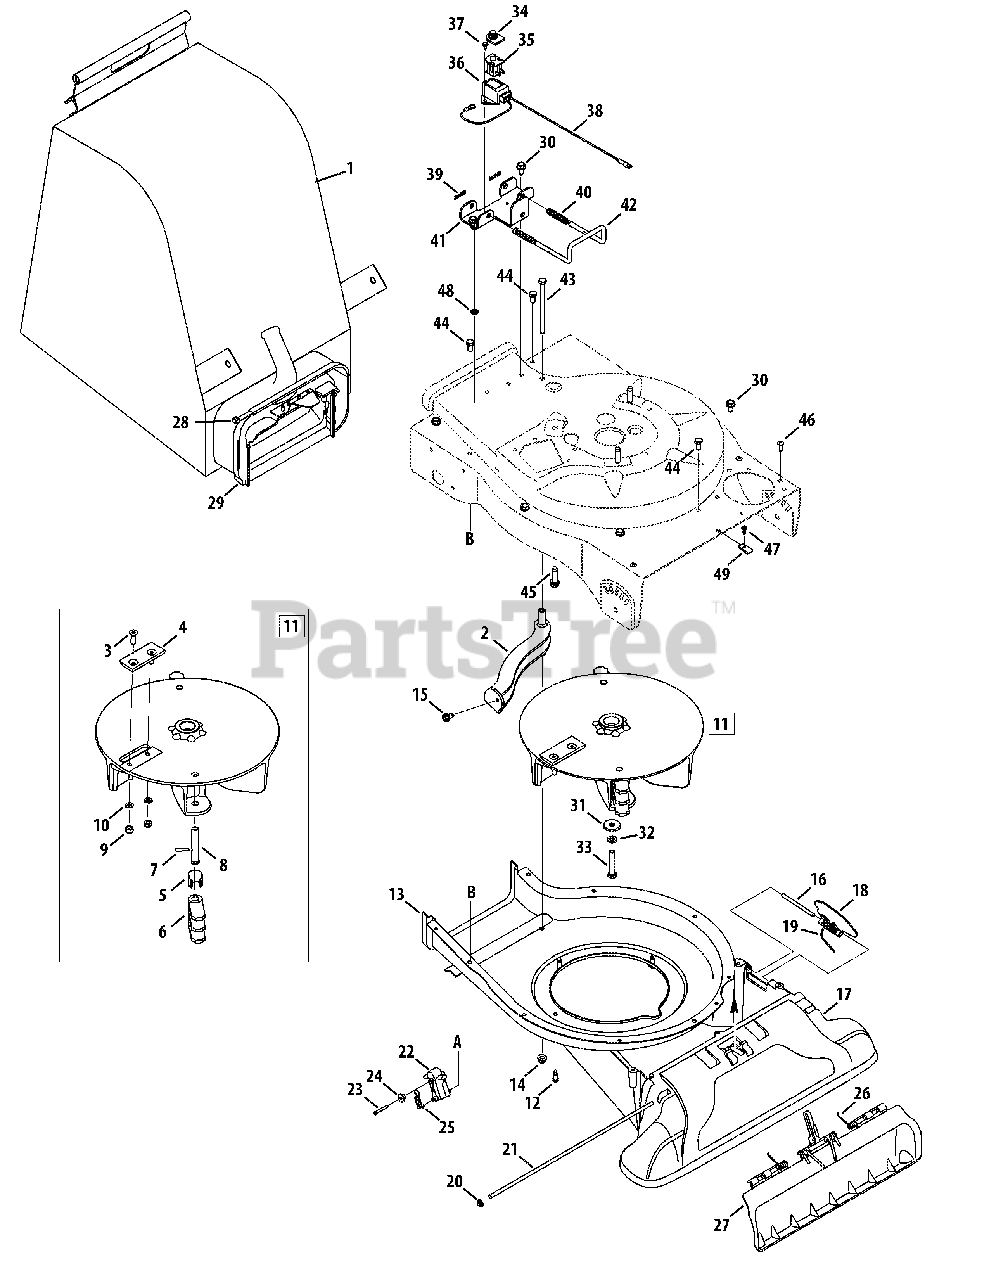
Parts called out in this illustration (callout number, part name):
1	Bag Assembly, TB
2	Screen Assembly
3	Hex Screw 5/16-24 x 1.0
4	Chipper Blade
7	Spiral Pin
8	Clevis Pin
9	Lock Nut, 5/16-24
10	Lock Washer, 5/16
11	Impeller Assembly
12	Shoulder Screw, #12-24 x.30 x.46
13	Lower Flail Housing
14	Flange Lock Nut 5/16-18
15	Screw, 5/16-18 x.500
17	Nozzle, TB
18	Base Adapter Door
19	Torsion Spring
20	Cap Speed Nut 1/4
21	Pivot Rod
22	Nozzle Door Lever, Red
23	Hex Screw, #8-18 x 1.25
24	Shoulder Spacer
25	Extension Spring
26	Nozzle Door Torsion Spring
27	Nozzle Door
29	Chute Assembly
30	Hex Index Screw, 5/16-12 x.750
31	Flat Washer.375 ID x 1.25 OD
32	Lock Washer 3/8
33	Hex Cap Screw 3/8-24 x 2.0
34	Switch Cover
35	Safety Switch
36	Safety Switch Cover
37	Hex Washer Screw #10-16 x.50
38	Wire Harness
39	Cotter Pin
40	Compression Spring
41	Mounting Bracket
43	Hex Cap Screw 5/16-18 x 4.5
44	Hex Cap Screw 5/16-18 x.625
45	Screw 3/8-16 x 1.00
46	Screw, #12-16 x.750
47	Screw #10 - 16 x.500
48	External L-Washer 5/16
49	Speed Nut
